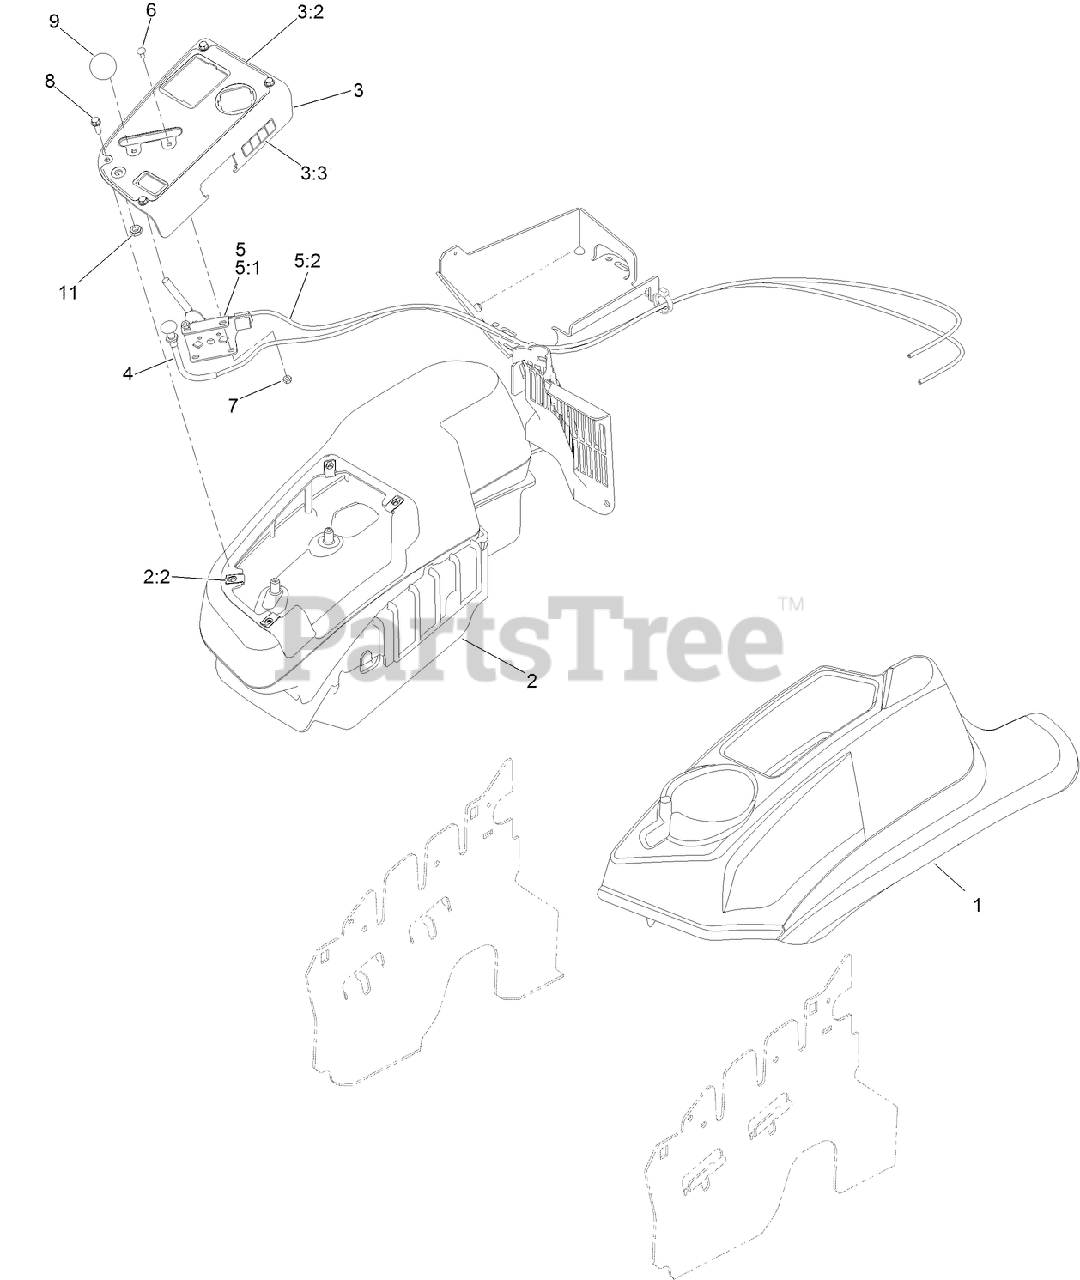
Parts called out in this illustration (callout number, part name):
1	CONSOLE-LH
2	RH CONSOLE ASM
3	CONTROL PANEL ASM
3:2	DECAL-CONTROL PANEL
3:3	DECAL-FUSES
4	CONTROL-CHOKE
5	THROTTLE CONTROL ASM
5:1	LEVER-THROTTLE
5:2	CABLE-THROTTLE
6	BOLT-CARR
7	NUT-LOCK, NI
8	SCREW-HWH
9	KNOB-BALL
11	NUT-HJ
